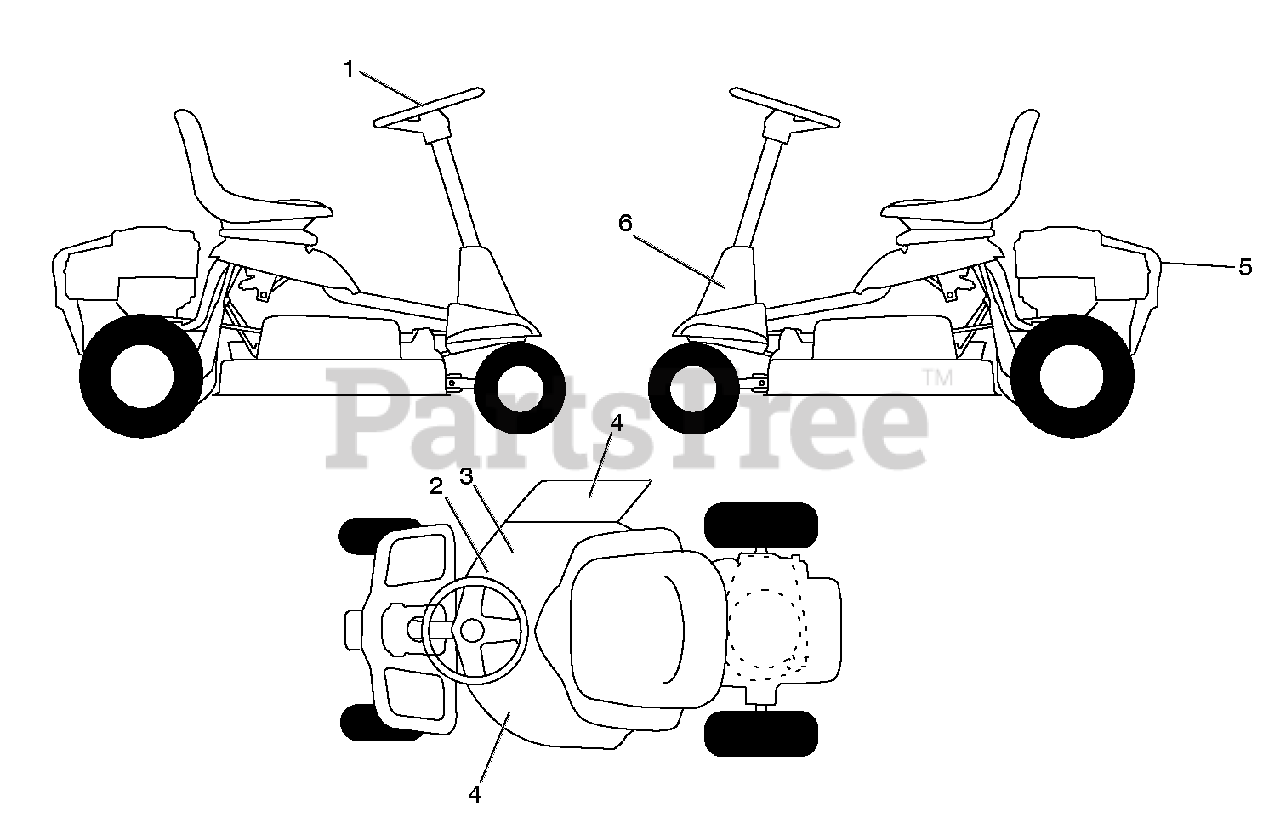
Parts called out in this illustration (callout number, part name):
1	DECAL, STEERING WHEEL
2	DECAL, V-BELT SCH 30"
3	DECAL, WARN. DEFLECT/CTFGR
4	DECAL, DECK/DEFLECTOR
5	DECAL, WARNING ENGINEGUARD
6	DECAL, STRBRCKT INSTALL BOOT
6	DECAL, BYPASS
6	MANUAL OPERATOR ENGLISH
6	MANUAL OPERATOR SPANISH
6	MANUAL OPERATOR FRENCH
6	MANUAL OPERATOR PORTUGUESE
